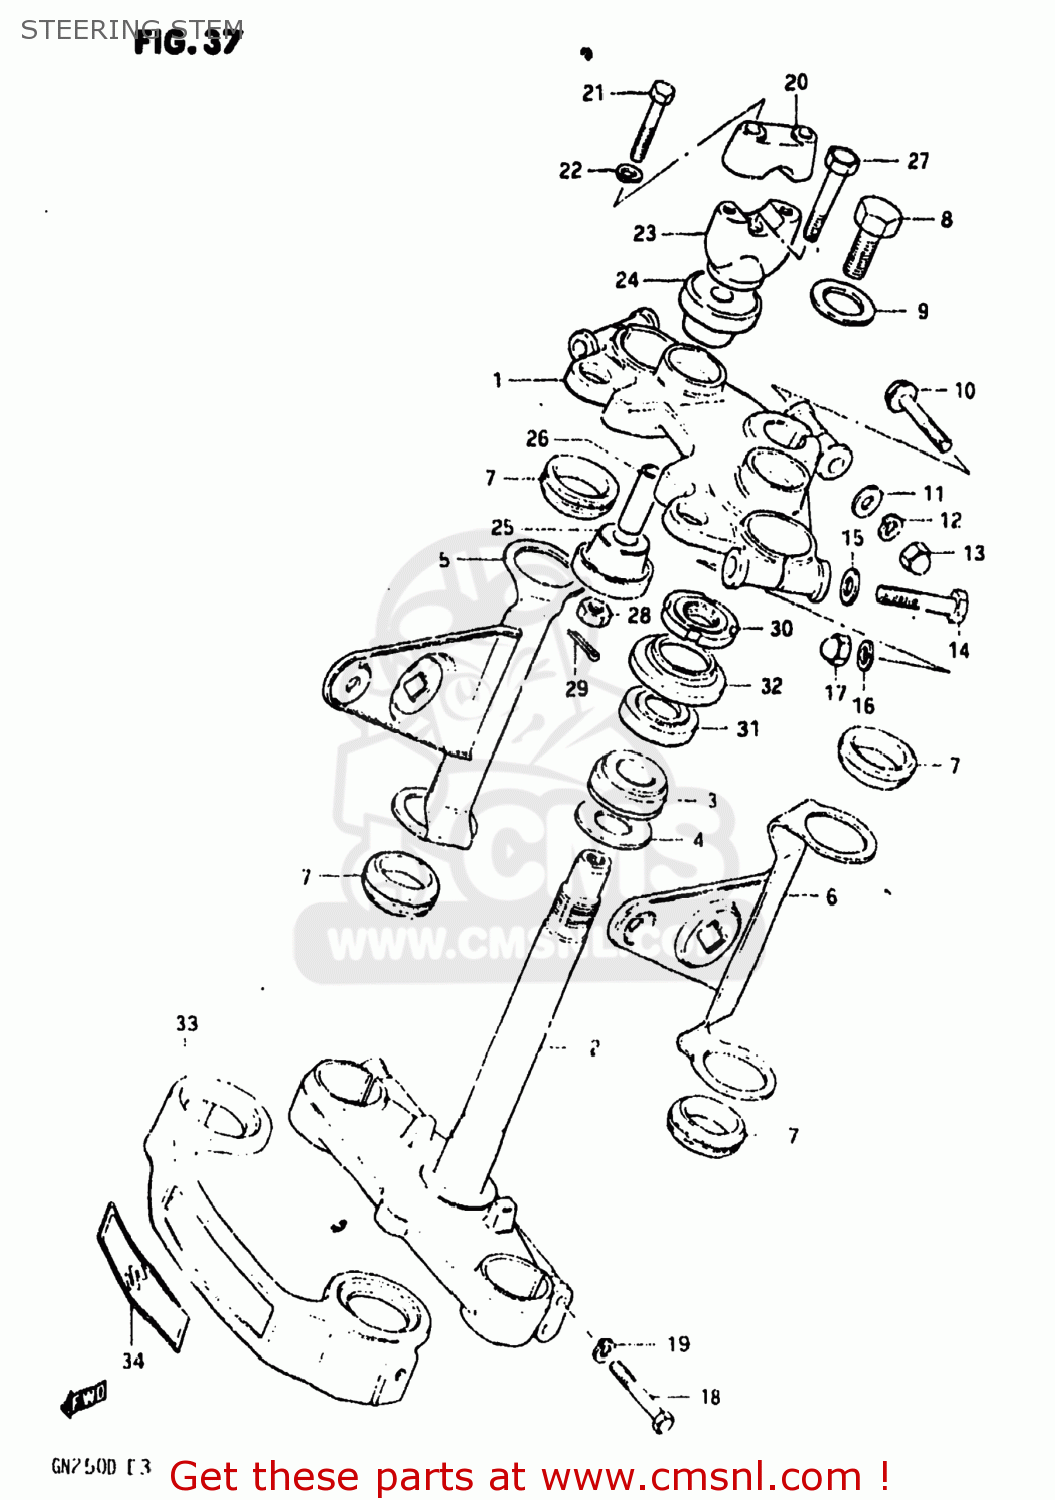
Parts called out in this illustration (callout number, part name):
1	HEAD,STEERING STEM
2	STEM,STEERING
3	BEARING
4	WASHER,THRUST
5	BRACKET,HEADLAMP,R
6	BRACKET,HEADLAMP,L
7	CUSHION,HEADLAMP BRACKET
8	BOLT(12X20)
9	WASHER
10	BOLT
11	WASHER
12	LOCK WASHER
13	NUT,M8X1.25X12
14	BOLT 10X55
15	WASHER
16	LOCK WASHER
17	NUT 10MM
18	BOLT 8X45
19	WASHER,LOCK,8.
20	HOLDER,HANDLE UPR
21	BOLT
22	LOCK WASHER
23	CLAMP,HANDLEBAR,LOWER
24	CUSHION,UPR
25	CUSHION
26	SPACER(10.2X14X46)
27	BOLT(10X78)
28	NUT
29	COTTER PIN
30	NUT,STEERING STEM(25X44X10)
31	TAPER,ROLLER BEARING
32	DUST SEAL,STEERING,UPPER
33	COVER,FRONT FORK
34	EMBLEM,FR FORK COVER
